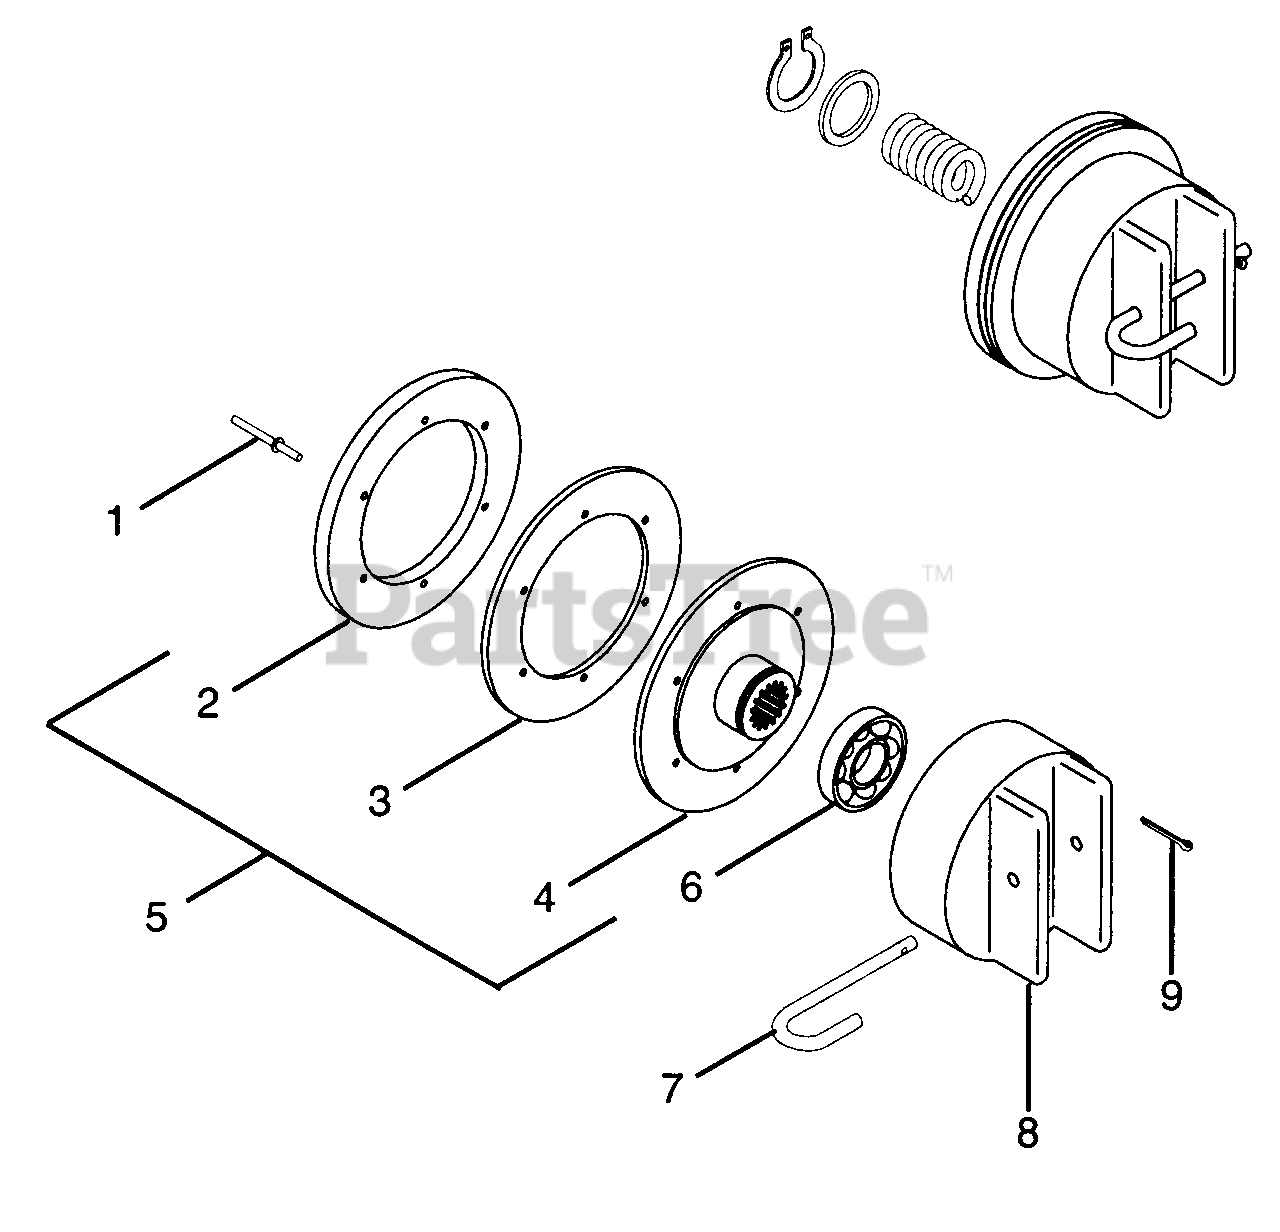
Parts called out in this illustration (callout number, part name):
1	Rivet
2	Lining-Clutch
3	Ring-Clutch
4	Disc-Clutch
5	Assembly-Clutch & Ring
6	Bearing-Ball 1.57 x 3.15 x .71
7	Pin-Clutch Spring
8	Trunion-Fwd-Rev Clutch
9	Pin-Cotter .062 x .75
